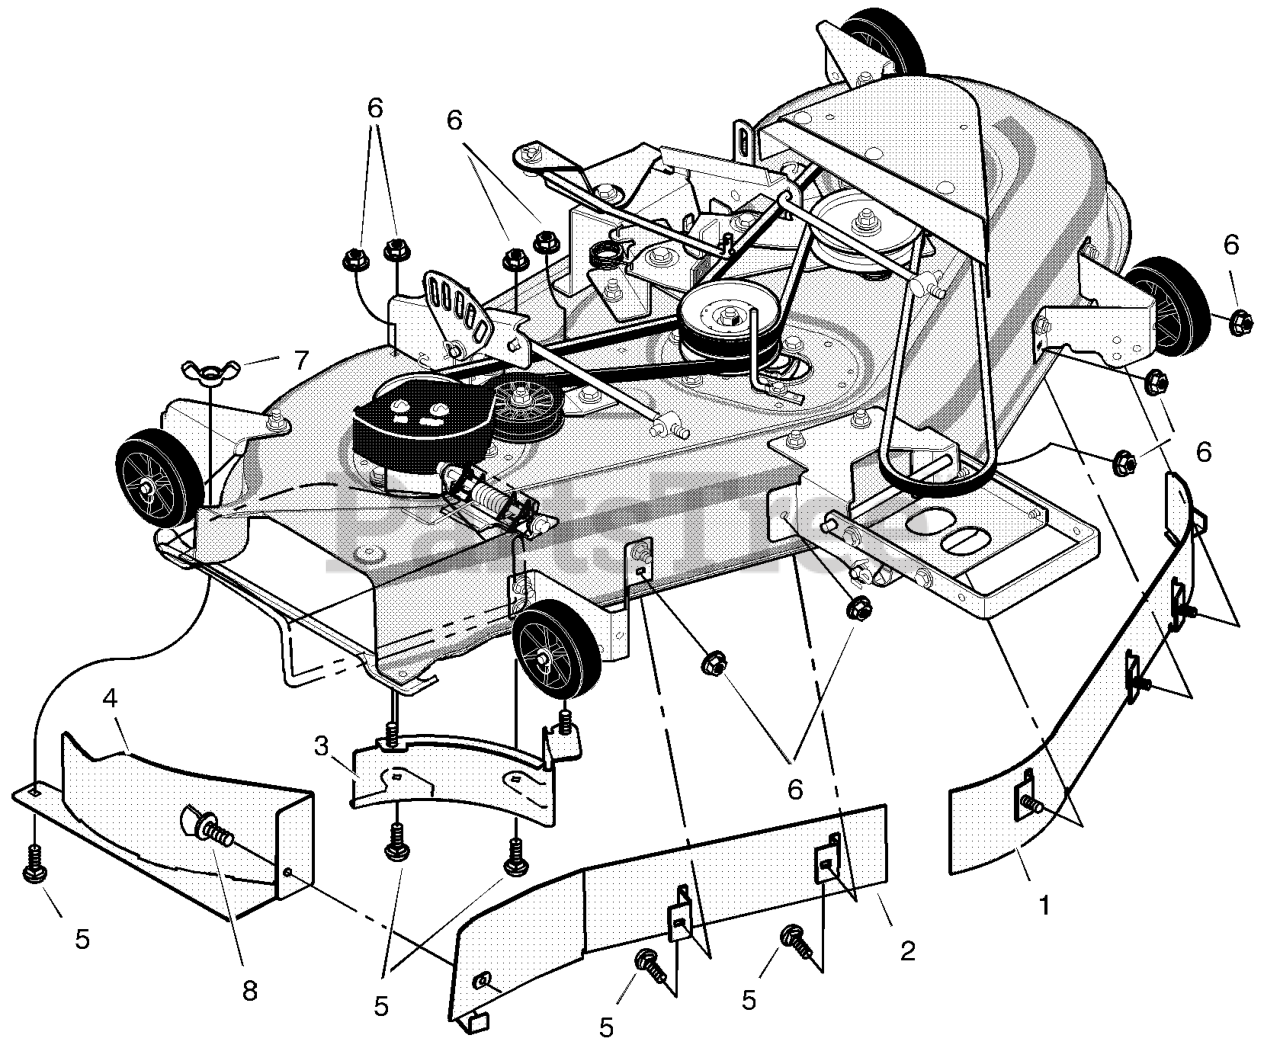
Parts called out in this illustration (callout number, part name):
1	Baffle, Left
2	Baffle, Right
3	Baffle Assembly, Rear
4	Plate, Mulcher
5	Bolt, Carriage
6	Nut, Flange
7	Wingnut
8	Screw, Thumb
